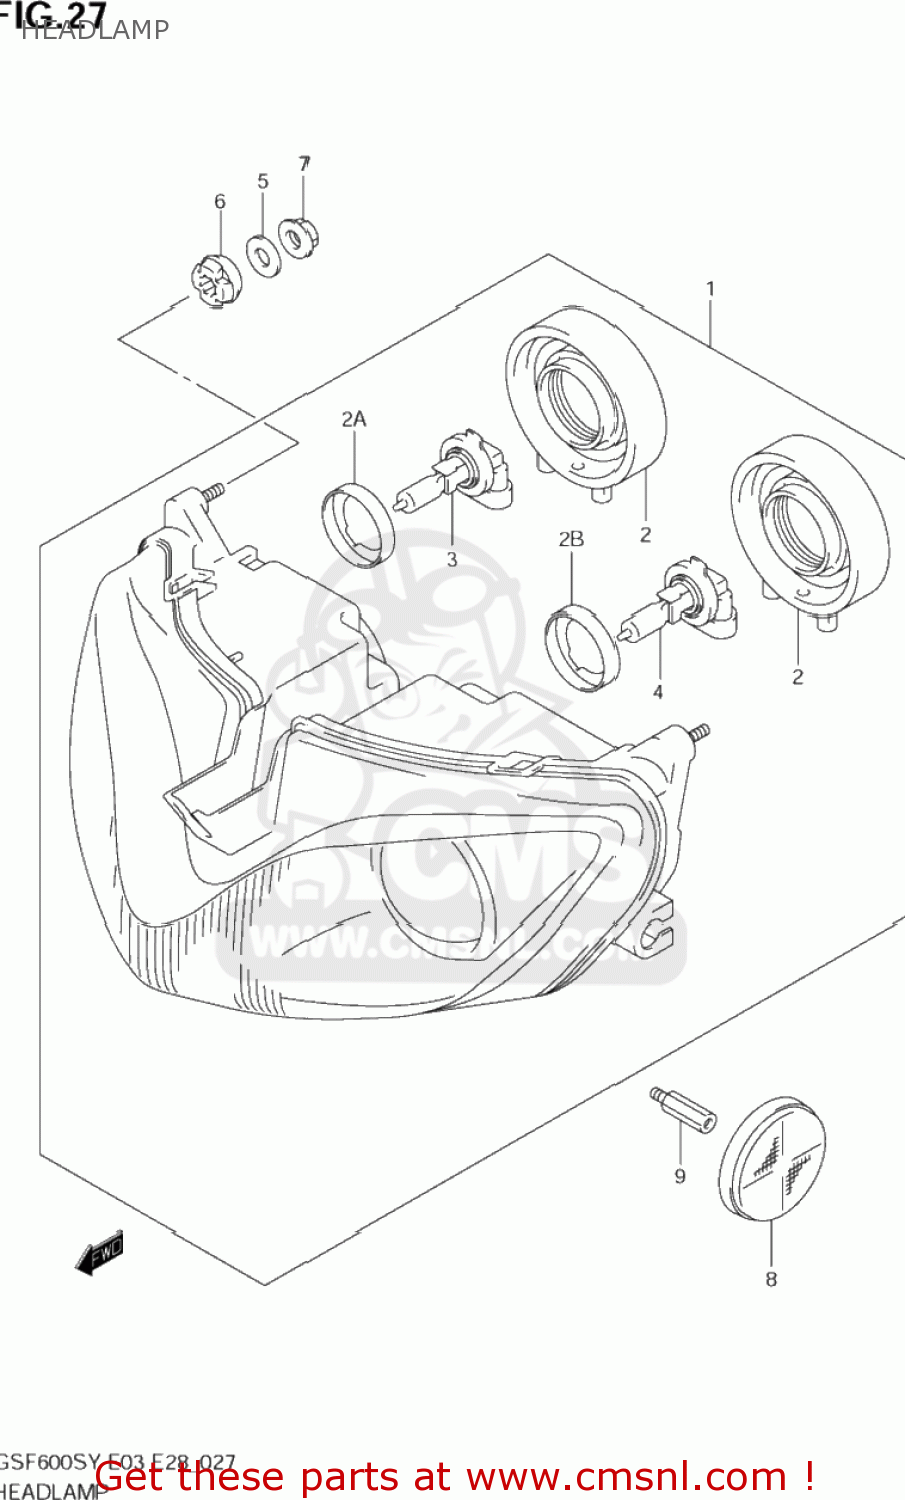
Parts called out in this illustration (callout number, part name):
1	HEADLAMP ASSY
2	SOCKET,COVER
2A	RING,HEADLAMP BULB,R
2B	RING,HEADLAMP BULB,L
3	BULB(12V60W,HB3,#9005)
4	BULB(12V51W,HB4,P22D)
5	WASHER(6.5X20X1.6)
6	CUSHION
7	NUT
8	REFLECTOR,REFLEX FR
9	BOLT(5X10)
